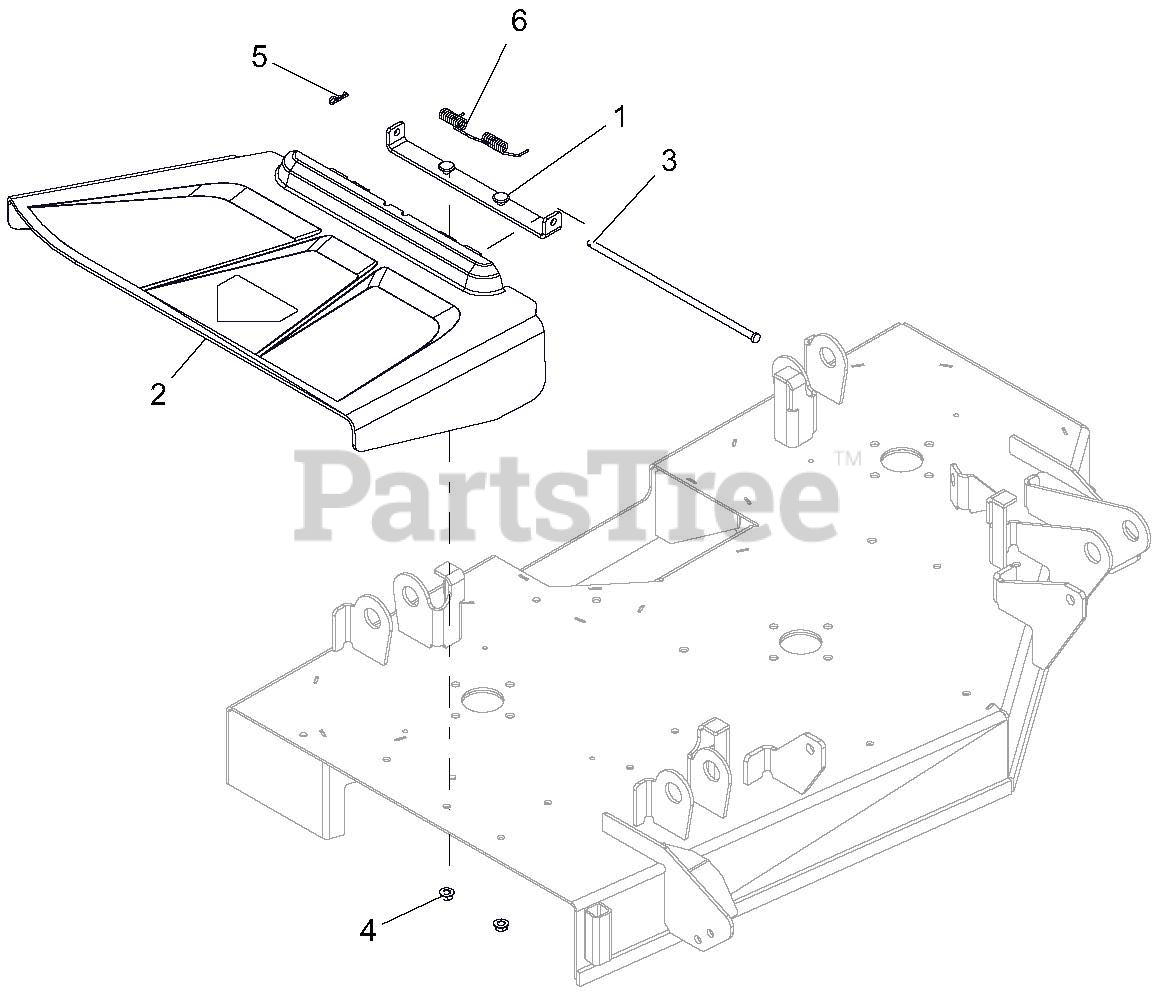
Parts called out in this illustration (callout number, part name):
1	WLDMT, CHUTE MT BRKT
2	CHUTE, SIDE DISCHARGE
3	PIN, 5/16 X 10.5
4	@NUT-LK-TOP-FLG .31-18 YWZC
5	PIN-HAIR INT .08X.18X1.18 YWZC
6	SPRING-TORSION
